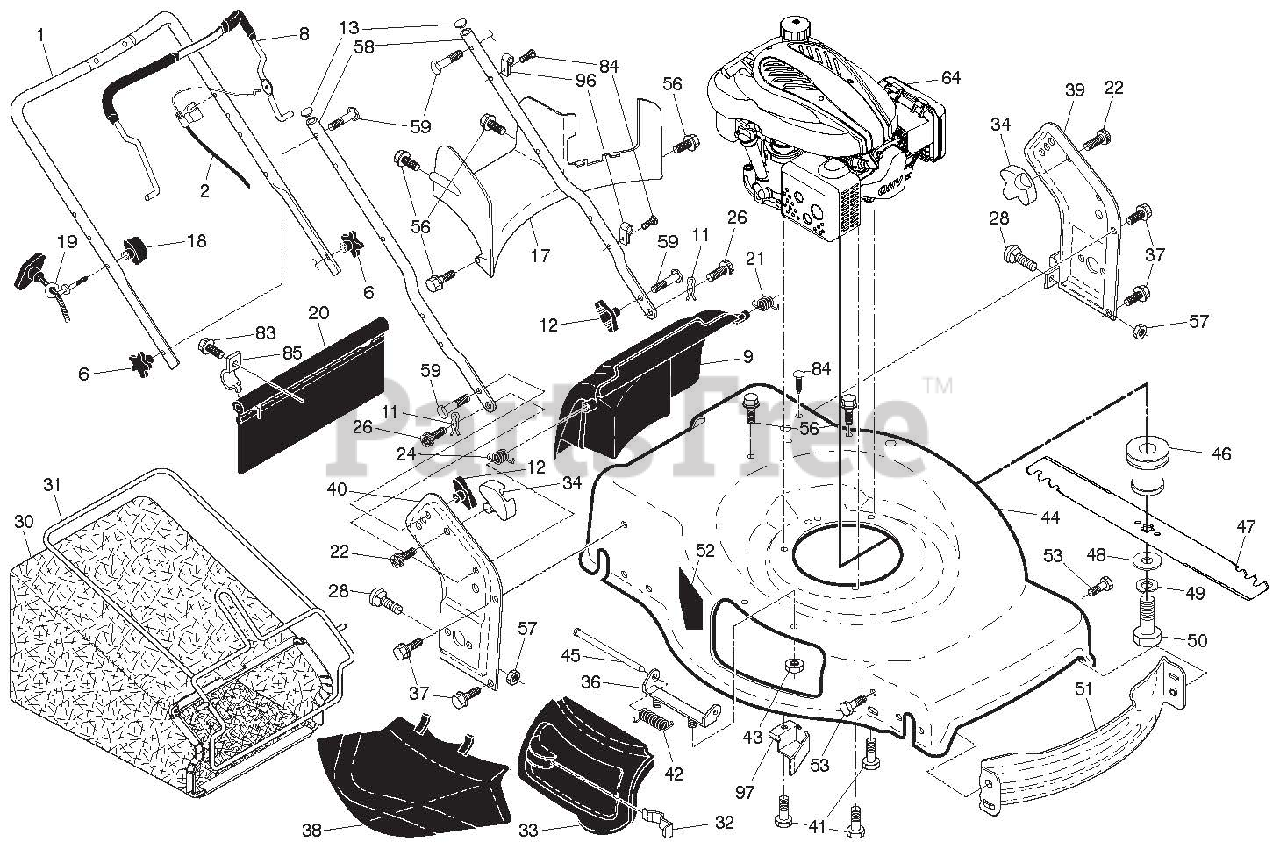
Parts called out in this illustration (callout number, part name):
1	UPPER HANDLE ASSEMBLY
2	CABLE, ENGINE ZONE CONTROL
6	Handle Knob
8	CONTROL BAR
9	REAR DOOR ASSEMBLY
11	HAIRPIN, DOOR/HANDLE PIVOT
12	HANDLE KNOB, STANDARD
13	PLUG, HANDLE BAR
17	REAR BAFFLE
19	ROPE GUIDE
20	REAR SKIRT
21	SPRING, REAR DOOR, LH, BLACK
22	SCREW, PANHEAD, TORX #20
24	SPRING, REAR DOOR, RH, GREY
26	SCREW, REAR DOOR/HANDLE PIVOT
28	BOLT, CARRIAGE
30	GRASSBAG
31	FRAME, GRASSBAG
32	LATCH, MULCHER DOOR
33	MULCHER DOOR
34	BRACKET, GRASSBAG
36	Hinge Bracket Assembly
37	BOLT.5/16-18HEX.WHS.HD.LCKSERR
38	DISCHARGE DEFLECTOR
39	HANDLE BRACKET, LH
40	HANDLE BRACKET, RH
41	Screw, Hex Head, Threaded, Rol
42	Spring, Torsion
43	LOCKNUT, HEX 1/4-20
44	KIT, LAWN MOWER HOUSING
45	Rod, Hinge
46	BLADE ADAPTER
48	WASHER, FLAT, HARDENED
49	Helical Lockwasher
50	BLT, HEX 3/8-24X1-3/8 G8
51	FRONT BAFFLE
52	DECAL, WARNING
53	BOLT.5/16-18HEX.WHS.HD.LCKSERR
56	Screw, Rear Baffle
57	NUT, HEX
58	BAR, LOWER HANDLE
59	Handle Bolt
64	ENGINE, LONCIN 159CC VERT.
84	FASTENER, PUSH
85	MOUNTING BRACKET, REAR SKIRT
96	Clip, Cable
97	BELT KEEPER
